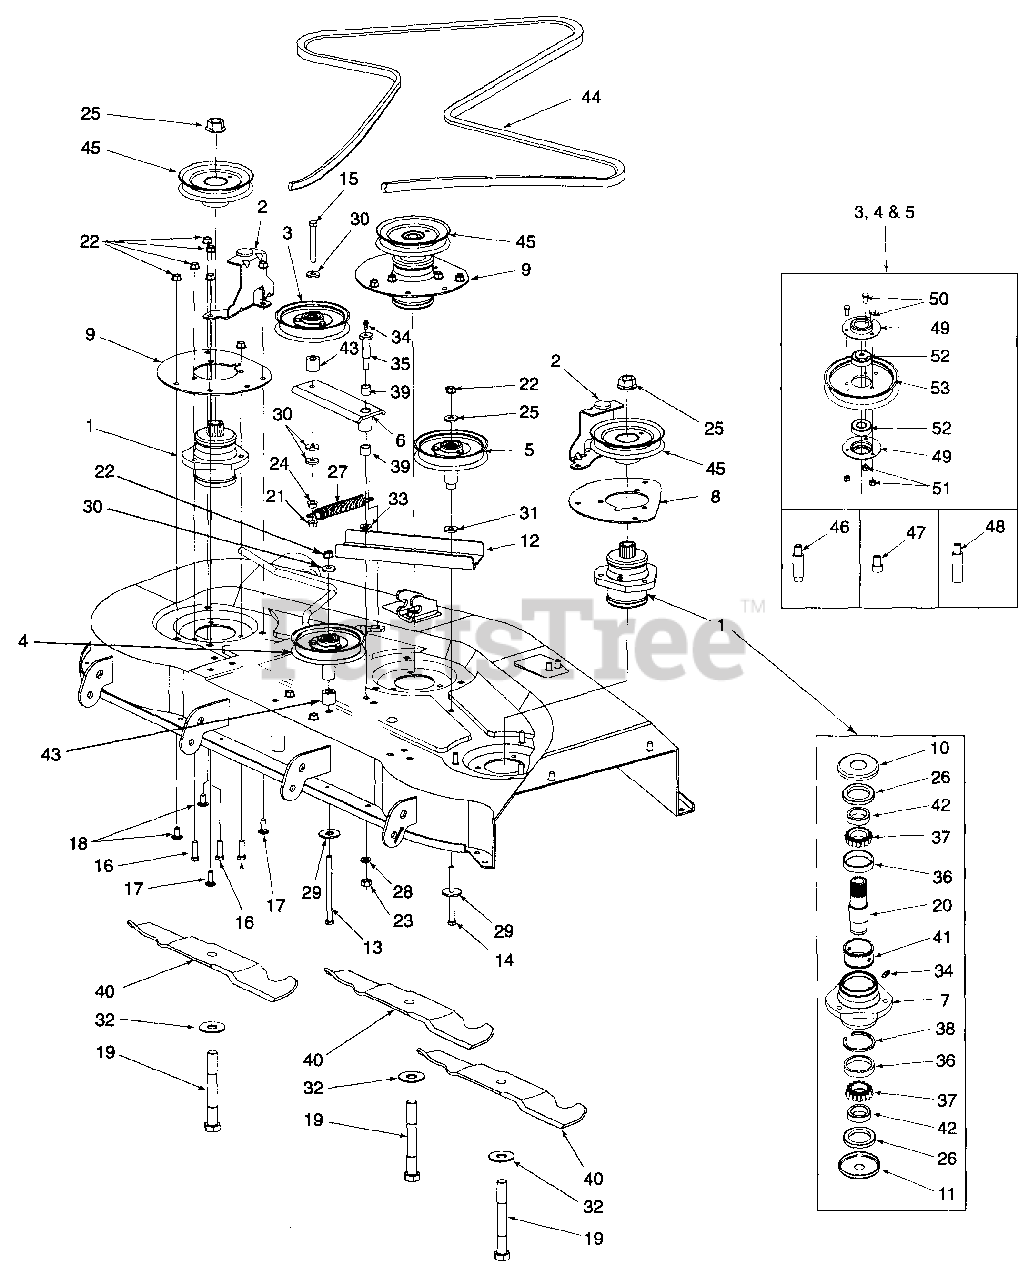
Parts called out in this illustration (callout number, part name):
1	Spindle Ass'y, Complete
4	Pulley Ass'y, 5" Idler
5	Pulley Ass'y, 5" Idler
14	Screw, Hex Cap, 3/8-16 x 4.5 GR5
15	Screw, Hex Cap, 3/8-24 x 3.75
16	Screw, Hex Cap, 3/8-16 x 1.25 GR5
17	Bolt, Carriage, 3/8-16 x 1.0 GR5
18	Bolt, Carriage, 3/8-16 x .75 GR5
19	Bolt, Hex Head, 3/4-16 x 6.0
20	Shaft, Spindle
21	Nut, Hex Center Lock Jam 3/8-24
22	Nut, Hex Flange Lock, 3/8-16
23	Nut, Hex, 7/16-14
24	Nut, Hex Top Lock, 3/8-24
25	Nut, Hex Flange, 3/4-16
26	Oil Seal
27	Spring, Extension
28	Washer, Lock, 7/16
29	Washer, Flat, 3/8 x 1.5 x .134
30	Washer, Flat, .385 x 1.0 x .135
31	Washer, Flat
32	Washer, Flat, .78 x 2.0 x .105
33	Washer, Flat, .469 x .875 x .105
34	Fitting, Grease
35	Shoulder Bolt
36	Cup, Bearing
37	Bearing, Cone
38	Spacer, Bearing
39	Bearing, Sleeve
40	Mower Blade
41	Spacer, Bearing Cup
42	Ring, Seal
43	Spacer, .410 x 1.0 x .80
44	V-Belt, B Section 153.0 Lg
45	Pulley, Spindle
46	Spacer, Front Deck Idler Pulley
47	Spacer, Idler Arm Pulley
48	Spacer, Rear Deck Idler Pulley
49	Cup, Bearing
50	Screw, Hex Cap, 1/4-20 x .62 GR5
51	Nut, Hex Insert Lock, 1/4-20
52	Bearing, Ball
53	Pulley, Flat Idler
